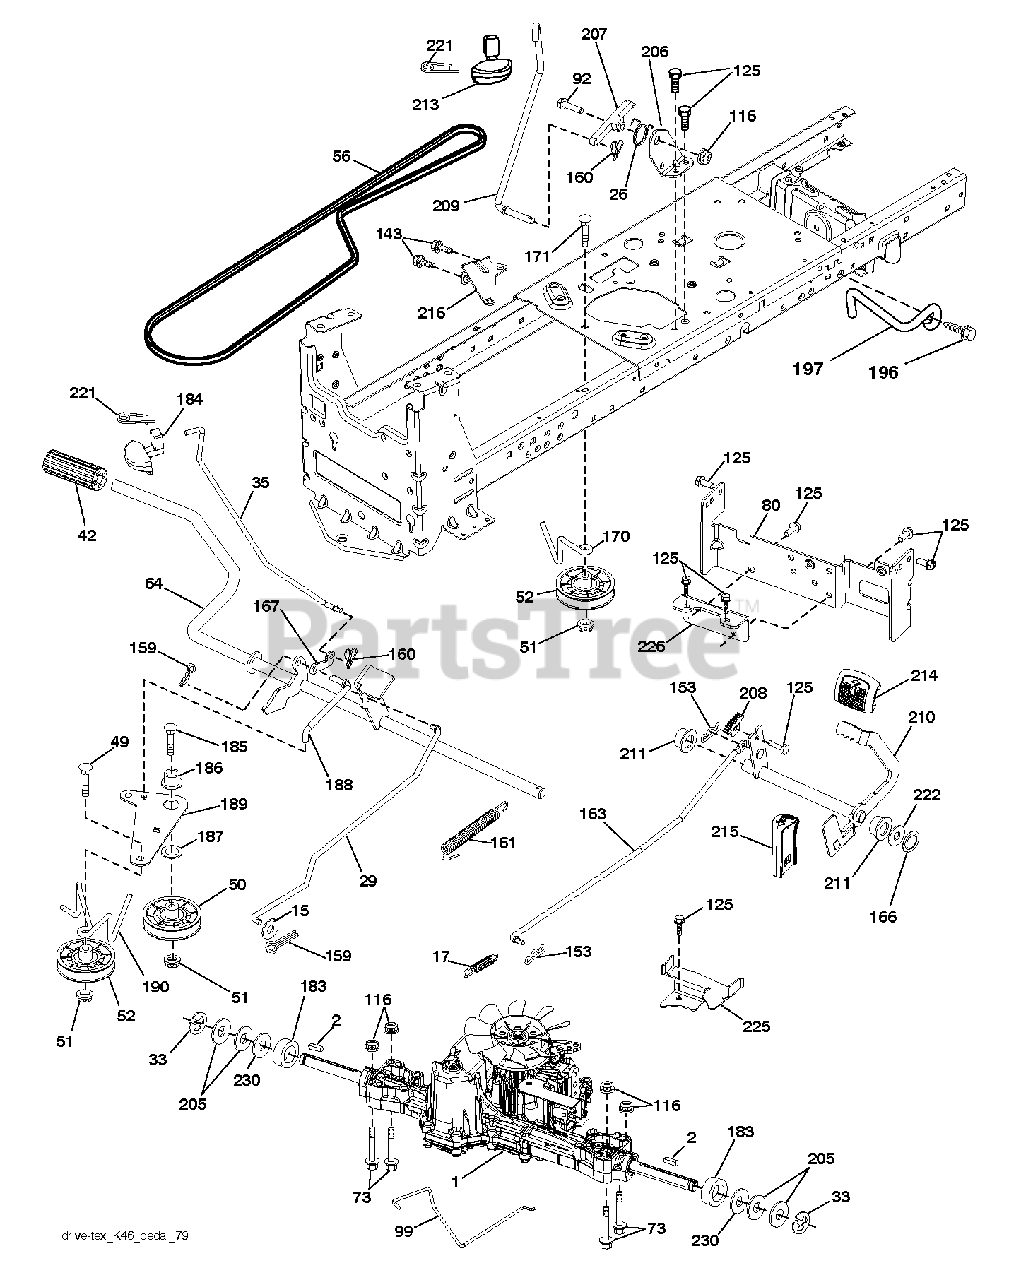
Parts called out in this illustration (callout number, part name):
2	SQUARE KEY
15	WASHER
17	SPRING, BREAK
26	SPRING.RETURN.CRUISE
29	ROD.BRAKE.K46
33	E-RING LT
35	ROD.BRKAE.PARKING.STEALTH
42	PEDAL COVER
50	IDLER.FLAT.910.OFFSET
52	IDLER.V-GROOVE.910.OFFSET
64	SHAFT.ASM.PEDAL.BRK.CN
73	BOLT HEX 5/16-18 GR 5
80	STRAP TORQUE
99	ROD.SPRING.BYPASS.K46.LT.Z
116	NUT LOCK HEX FLANGE 5/16-18
125	SCREW
143	SCREW LT
153	RETAINER M
159	COTTER PIN
160	RETAINER CLIP
161	SPRING, RETURN LT
166	NUT.PUSH.625
167	LATCH BRAKE PARKING
170	KEEPER.V-IDLER.CENTER.
183	SPACER AXLE
184	HANDLE.PRKG.BRAKE.STLTH.TX505
186	SPACER.RETAINER
188	LINK.CLUTCH.GROUND DRI
189	BELLCRANK.GRDDRIVE.NST
190	KEEPER.BELLCRANK.DRIVE
196	SCREW 3/8-16X1
197	LINK.CLUTCH.ANIT-ROTAT
206	BRKT.MOUNT.LATCH.CRUIS
207	LATCH.CONTROL.CRUISE
208	GEAR.SECTOR.CONTROL.CR
209	ROD.CONTROL.CRUISE.STE
210	ROCKER.ASM.PEDAL.CONTR
211	BEARING RER
213	KNOB.CONTROL.CRUISE
214	PAD PEDAL FORWARD
215	PEDAL.REVERSE.TEX.GT.4
216	BRKT.PULLEY.IDLER.WTEX
221	RETAINER.SPRING.CLIP.H
222	WASHER 21/32 X 1-1/4 X 10 GA.
225	KEEPER.BELT.TRANSAXLE.
226	BRACKET MOUNT TORQUE
